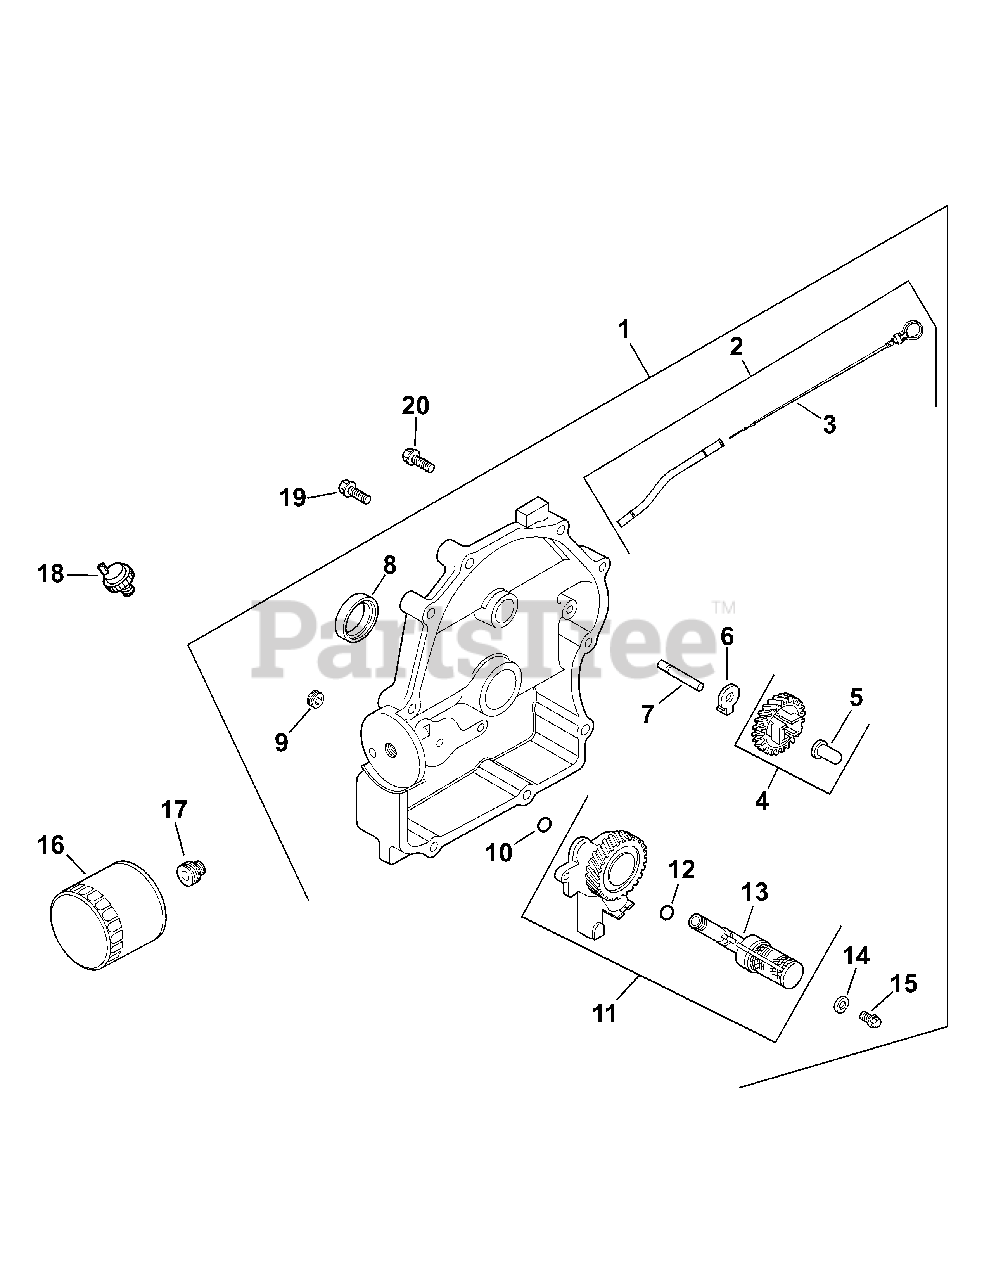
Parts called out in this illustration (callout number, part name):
1	Plate, closure assembly (Includes 2-15)
2	Kit, tube w/dipstick (Includes 3)
4	Kit, governor gear (Includes 5)
5	Pin, governor regulating
7	Shaft, governor gear
8	Seal, oil (PTO end)
9	Plug, pipe 1/8" (2)
11	Oil pump assembly (Includes 12,13)
12	O-Ring, oil pick-up
13	Pick-up, oil
14	Washer, plain 6 mm (2)
15	Screw, hex. flange M6x1.0x25 (2)
16	Filter, oil
17	Nipple, oil filter
18	Switch, pressure
19	Screw, hex. flange M8x1.25x45 (9)
20	Screw, hex. flange M8x1.25x45
